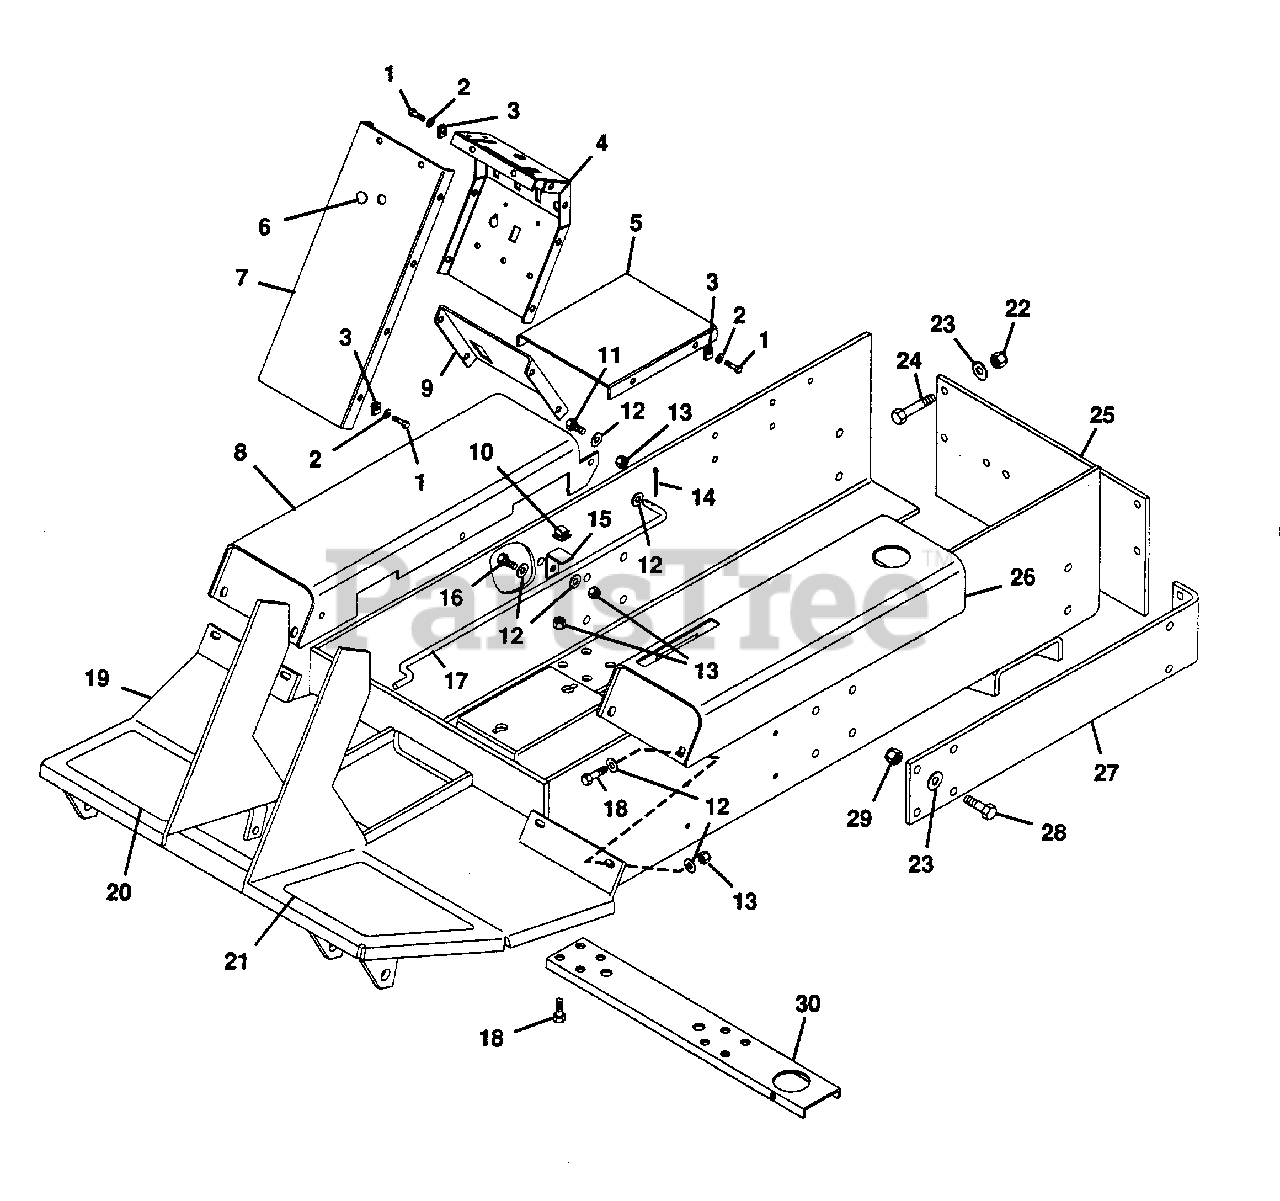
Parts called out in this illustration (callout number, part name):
1	Screw, Machine 1/4-20 PHD
2	Washer, Flat .281x.625x.065
3	Nut, Retainer
4	Panel, Silk Screen Instrument
5	Panel, Access Silk Screen
6	Plug, Hole
7	Panel, Front Silk Screen
8	Fender, Silk Screen R.H.
9	Panel, Brake Lock Silk Screen
10	Clip, Wire
11	Bolt, Hex 3/8-16x.75
12	Washer, Flat .406x.812x.065
13	Nut, Lock 3/8-16
14	Pin, Cotter .094x.75
15	Bracket, Stay Rod
16	Bolt, Hex 3/8-16x1.00
17	Rod, Stay
18	Bolt, Hex 3/8-16x.875
19	Weldment, Frame
20	Cover, R.H. Foot
21	Cover, L.H. Foot
22	Nut, Lock 1/2-13
23	Washer, Flat .531x1.062x.095
24	Bolt, Hex 1/2-13x2.75
25	Plate, Bumper
26	Fender, Silk Screen L.H.
27	Bumper
28	Bolt, Hex 1/2-13x1.25
29	Nut, Lock 1/2-13
30	Brace, Frame
